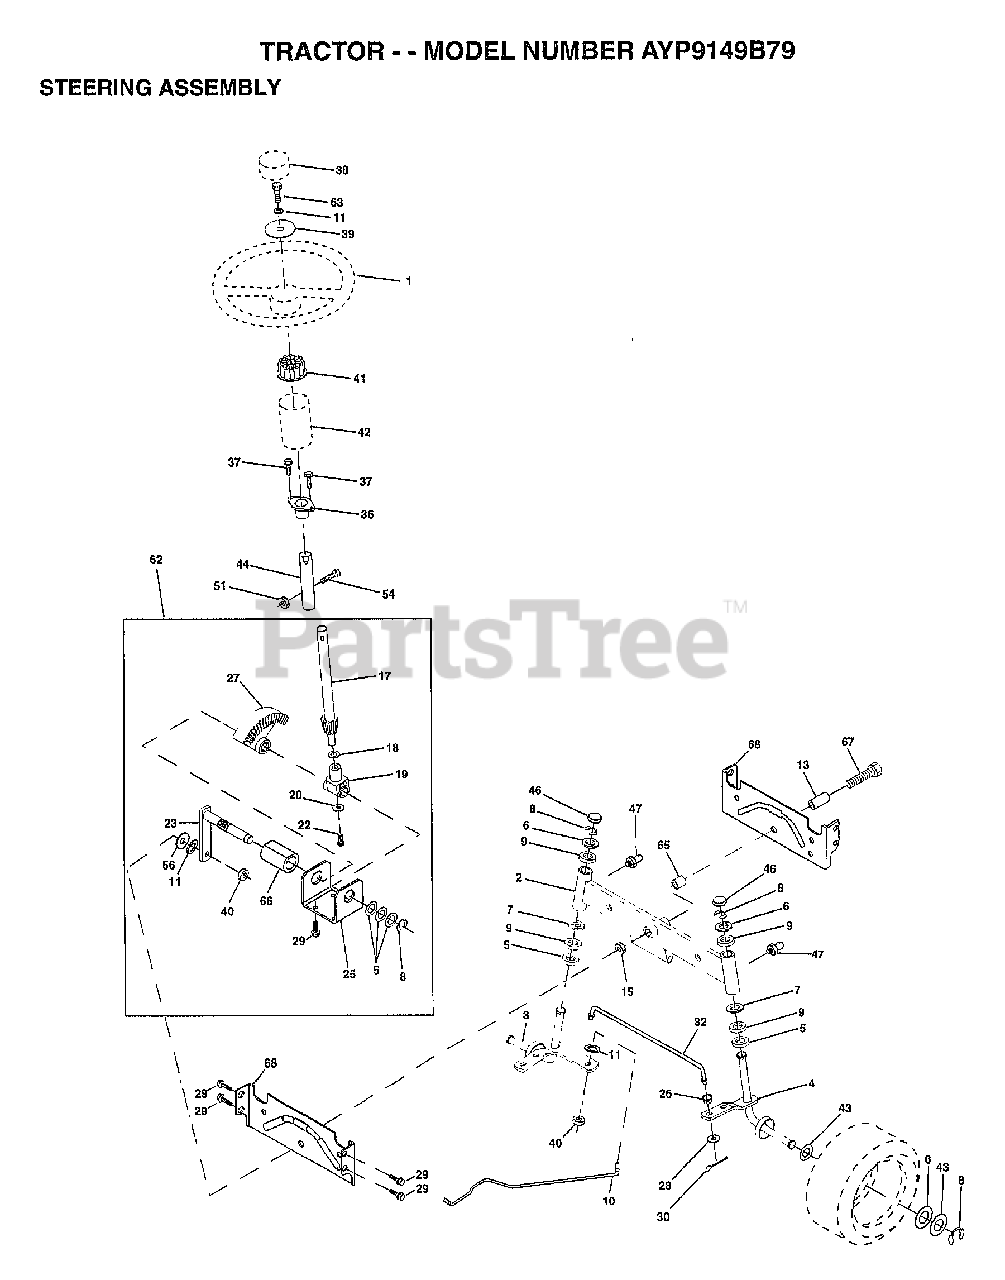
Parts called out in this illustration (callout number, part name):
1	WHEEL STR AYP BLK
2	AXLE ASM
3	SPINDLE.ASM.LH
4	"SPINDLE ASM,RH"
5	WASHER .T
6	WASHER
7	WASHER
8	RING
9	COL. SRTG. BEAR.
10	DRAGLINK-STAMPED
11	LOCKWASHER
13	BEARING AXLE
15	"NUT-LOC,FLANGE LT"
17	SHAFT ASM STEERIN
18	THRUST WASHER
19	SUPPORT.SHAFT
21	LOCKWASHER
22	SCREW.SCKTHD.CAP
25	BRKT-STEERING
26	BUSHING.DRAGLINK
27	GEAR SECTOR
28	WASHER
29	SCREW
30	COTTER PIN
32	TIE ROD
36	BUSHING.STEERING
37	"SCREW-TT,10-32 FL"
38	CAP STEER AYP
39	WASHER T
40	GRIPCO NUT
41	ADAPTER LT
42	BOOT.STEER.PL
43	WASHER
44	EXT SHAFT STEERIN
46	CAP
47	ZERK M
51	NUT
54	BOLT
62	KIT STEERING ASM
63	BOLT
65	SPACER AXLE
66	"BEARING-ARM,PITMA"
67	BOLT
68	BRACE AXLE
